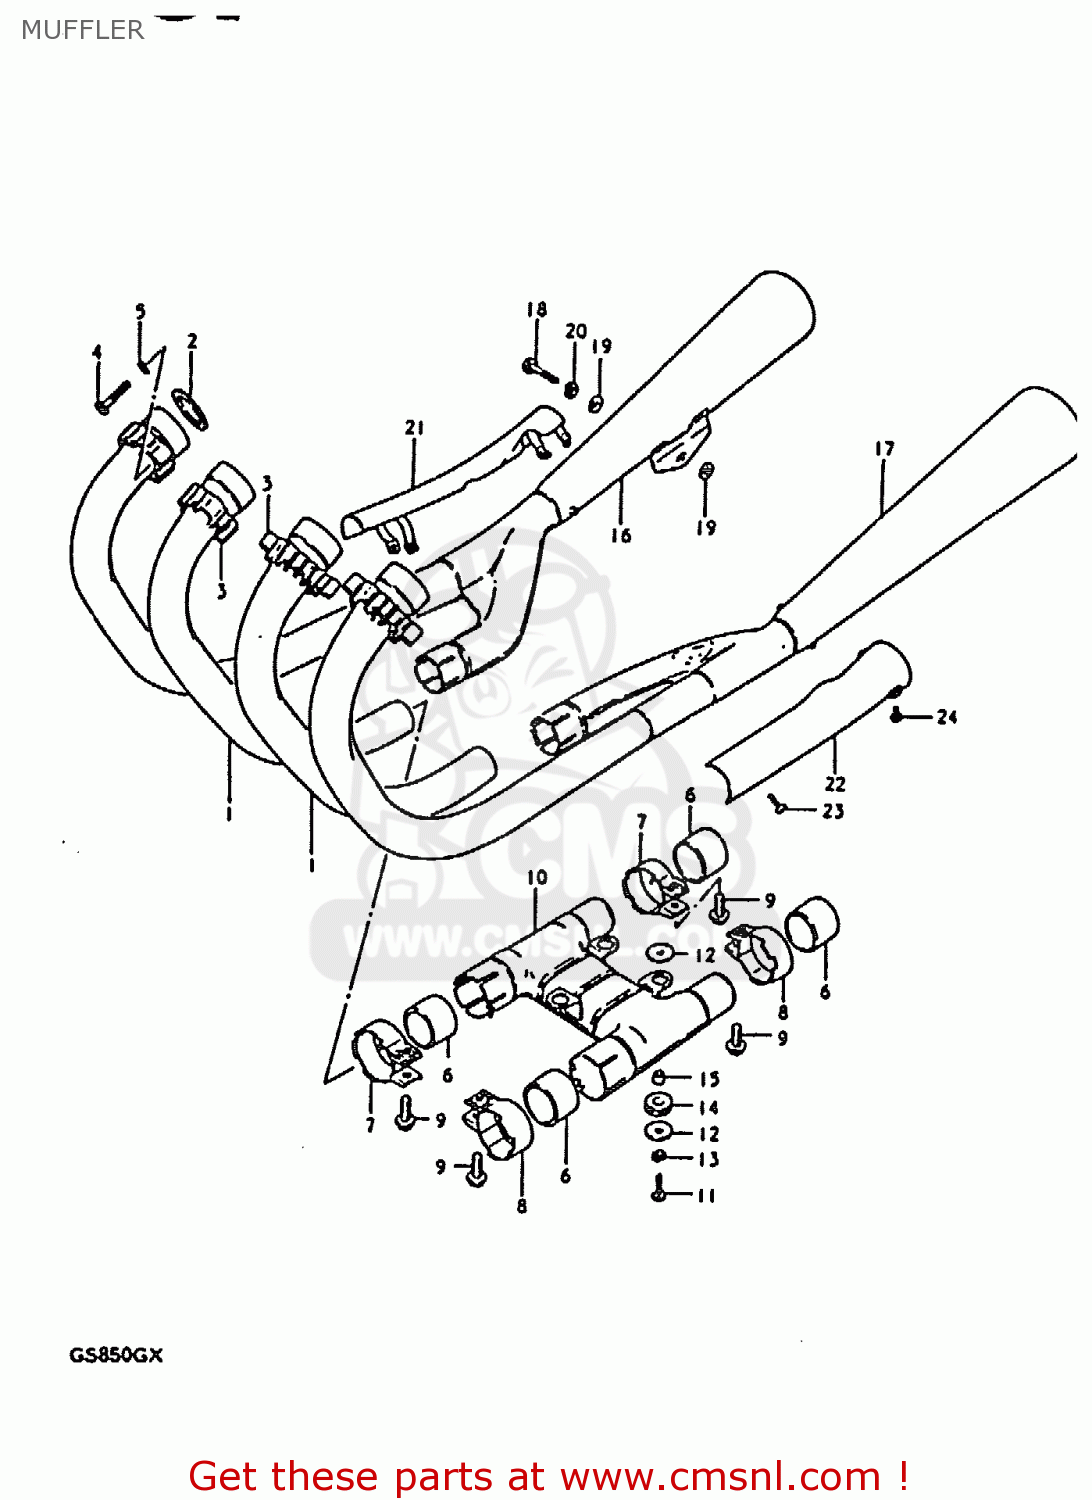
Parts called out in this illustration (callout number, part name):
1	PIPE,CENTER EXHAUST
2	GASKET,EXHAUST PIPE (NAS)
3	CLAMP,EXHAUST PIPE
4	BOLT
5	LOCK WASHER
6	CONNECTOR,MUFFLER
7	CLAMP,MUFFLER CONNECTOR,R
8	CLAMP,MUFFLER CONNECTOR,L
9	BOLT
10	BODY,PREMUFFLER
11	BOLT
12	WASHER (6.5X24X1.6)
13	LOCK WASHER
14	CUSHION
15	SPACER(6.5X10.5X6.5)
16	BODY,MUFFLER
17	BODY,MUFFLER
18	BOLT 10X30
19	WASHER
20	LOCK WASHER
21	COVER,MUFFLER
22	COVER,MUFFLER
23	SCREW
24	SCREW
